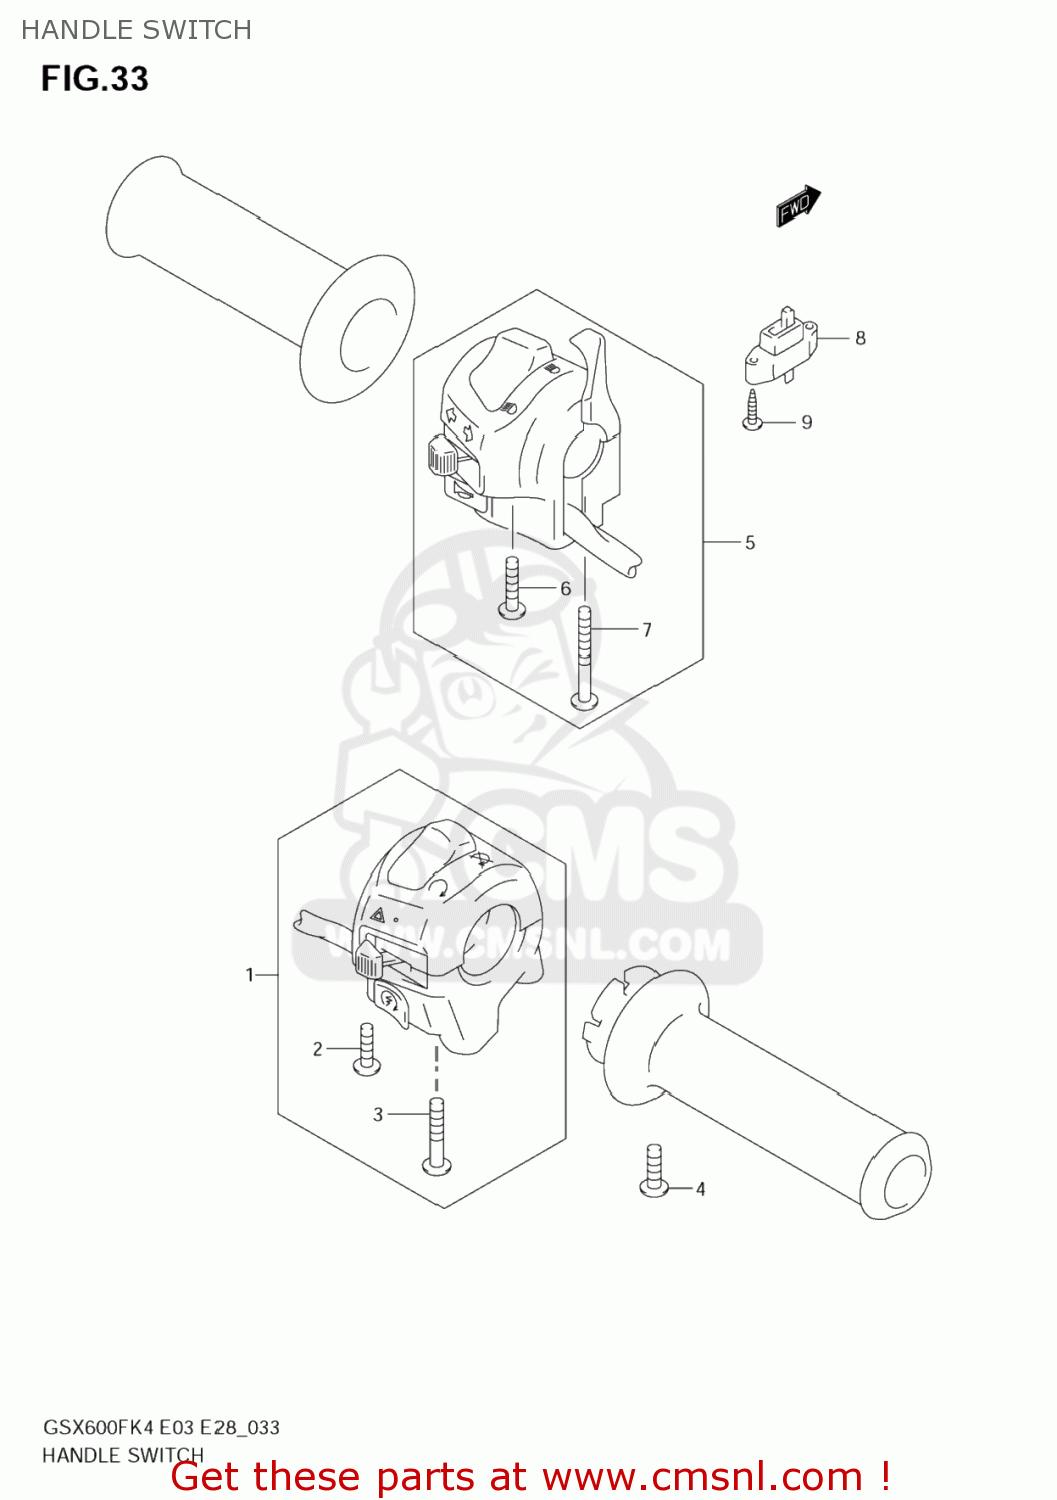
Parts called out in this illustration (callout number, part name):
1	SWITCH ASSY,HANDLE,R
2	SCREW
3	SCREW
4	SCREW
5	SWITCH ASSY,HANDLE,L
6	SCREW
7	SCREW
8	SWITCH ASSY,CLUTCH
9	SCREW(3X14)
